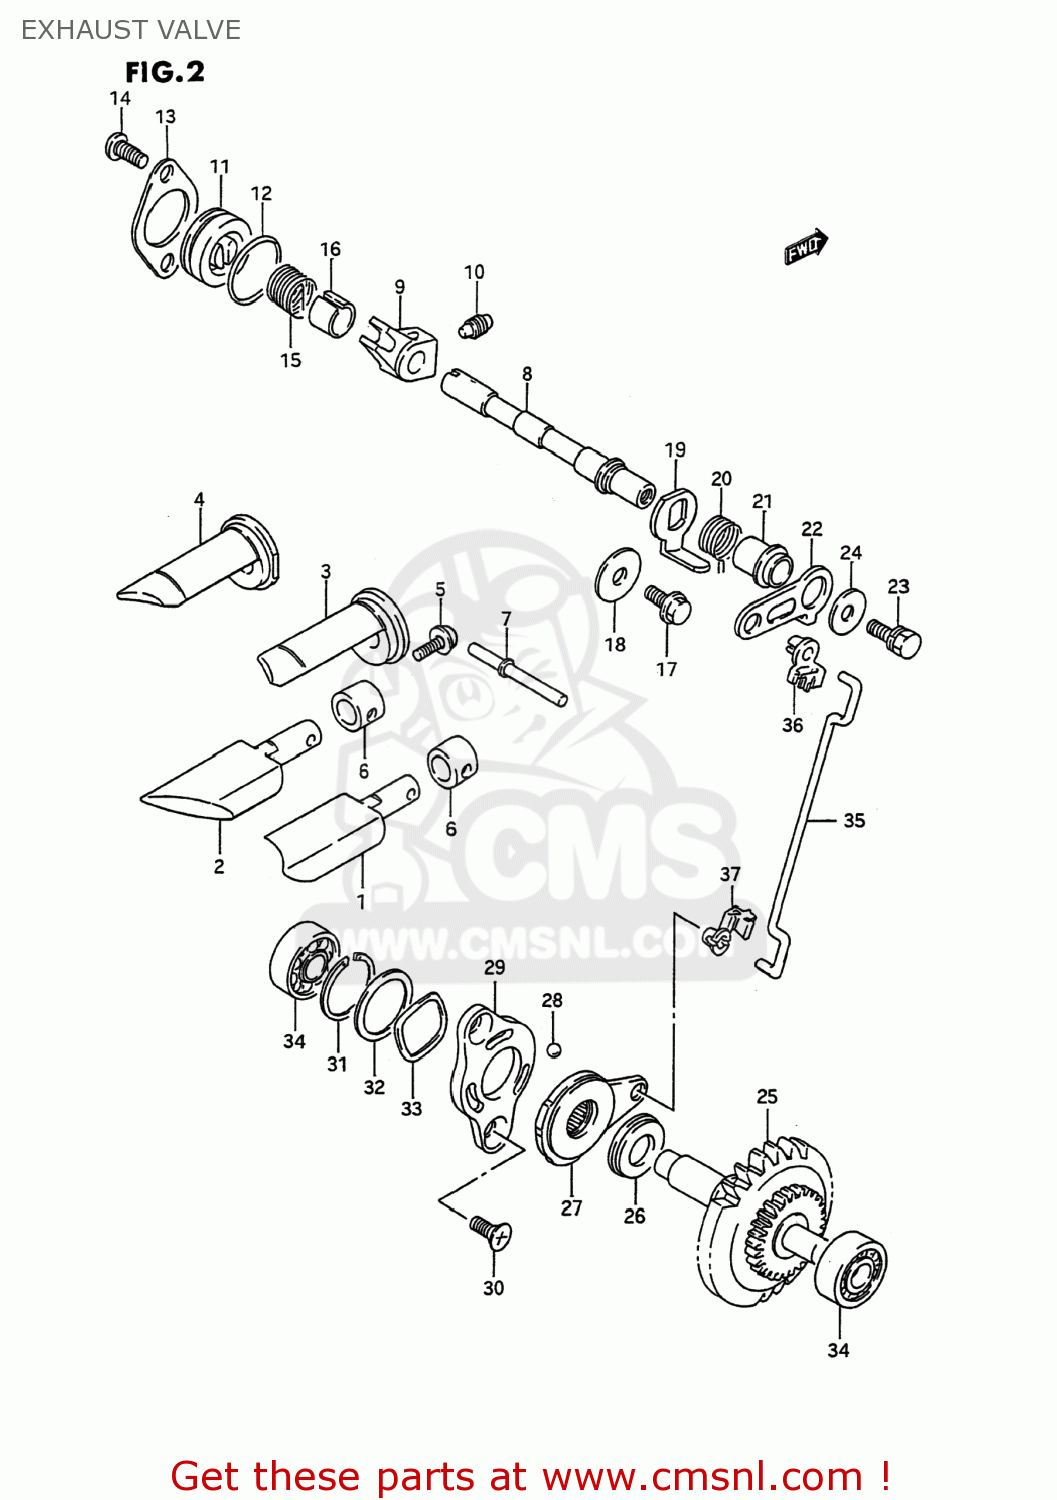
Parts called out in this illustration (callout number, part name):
1	VALVE,EXHAUST,R
2	VALVE,EXHAUST,L
3	GUIDE,EXHAUST VALVE,R
4	GUIDE,EXHAUST VALVE,L
5	SCREW
6	HOLDER,EXHAUST VALVE
7	PIN,EXHAUST VALVE 48.5MM
8	SHAFT,EXHAUST VALVE
9	ARM,EXHAUST VALVE SHAFT
10	SCREW(6X10)
11	CAP,EXHAUST VALVE
12	O RING(D:1.9,ID:22.6)
13	RETAINER,EXHAUST VALVE
14	SCREW
15	SPRING
16	SPACER,EXHAUST VALVE SPRING
17	BOLT
18	WASHER
19	LEVER,EXHAUST VALVE NO
20	SPRING
21	SPACER,EXHAUST VALVE
22	LEVER,EXHAUST VALVE NO.1
23	BOLT
24	WASHER (5.5X16X1.2)
25	GOVERNOR ASSY,EXHAUST VALVE
26	BEARING(10X22X2.8)
27	ACTUATOR,EXHAUST VALVE
28	BALL
29	STARTER,EXHAUST VALVE ACTUATOR
30	SCREW(5X10)
31	CIRCLIP
32	SHIM(19.1X25X0.3)
33	WASHER
34	BEARING(8X22X7)
35	ROD,EXHAUST VALVE
36	BUSH,EXHAUST VALVE ROD NO.1
37	BUSH,EXHAUST VALVE ROD NO.2
